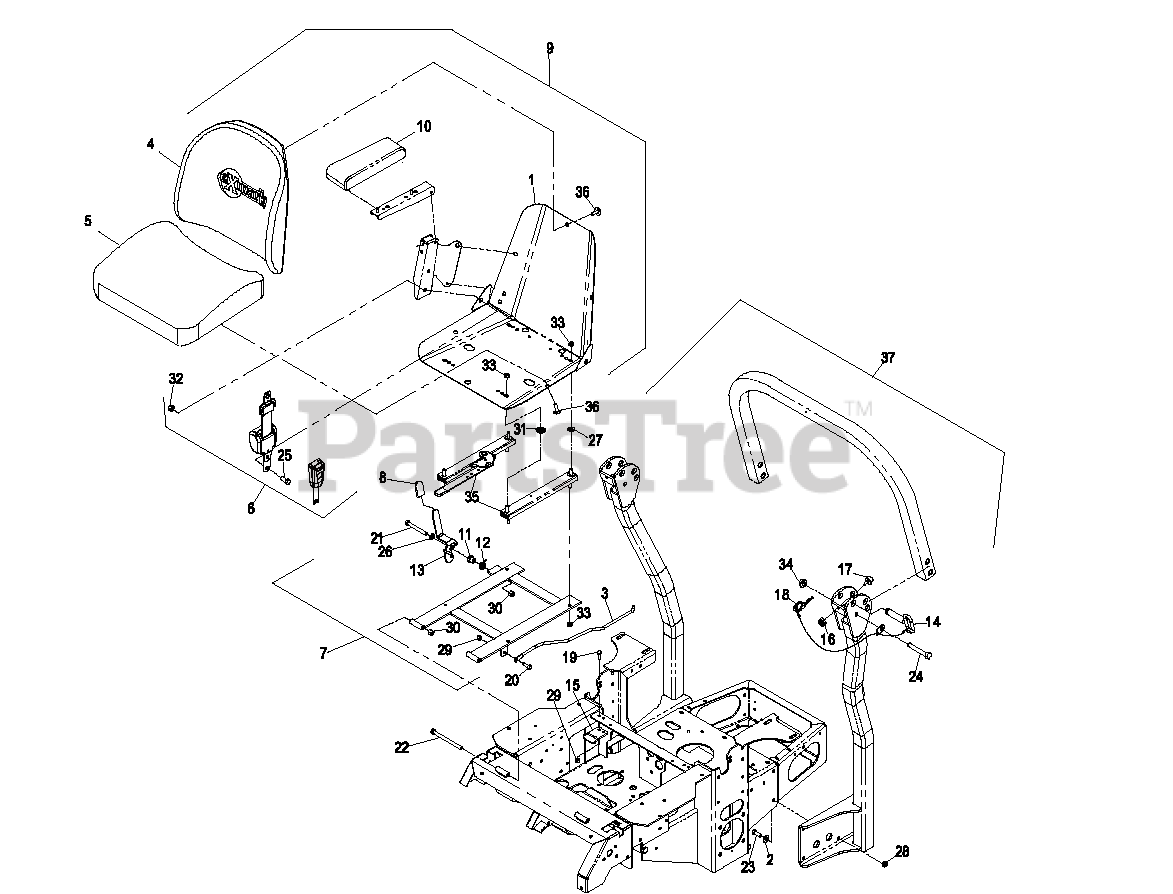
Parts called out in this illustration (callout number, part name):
1	FRAME-SEAT
2	WASHER-BELLEVILLE
3	ROD-RETAINER, SEAT
4	CUSHION,SEAT BACK
5	CUSHION,SEAT BOTTOM
6	RETRACTABLE SEATBELT KIT
7	ASM,SEAT FRAME
8	GRIP-LEVER
9	KIT,SEAT W/ARMREST ADJ.
10	CUSHION,ARMREST RH
10	CUSHION,ARMREST LH
11	BUSHING-LATCH, SEAT
12	SPRING-TORSION
13	LATCH ASM
14	PIN-FOLD, ROPS
15	CATCH-LATCH, SEAT
16	NUT-LOCK, NI
17	BUMPER-RUBBER
18	HAIRPIN
19	SCREW-HH
20	SCREW-HH
21	SCREW-HH
22	SCREW-HH
23	SCREW-HH
24	SCREW-HH
25	SCREW-HH
26	WASHER-FLAT
27	WASHER-FLAT
28	NUT-HHF, WHIZ
29	NUT-LOCK, NI
30	NUT-LOCK, NI
31	SPACER-TRACK
32	NUT-LOCK
35	TRACK-SEAT
36	BOLT-SEAT
37	Frpsl Kit, Rops Lhp
